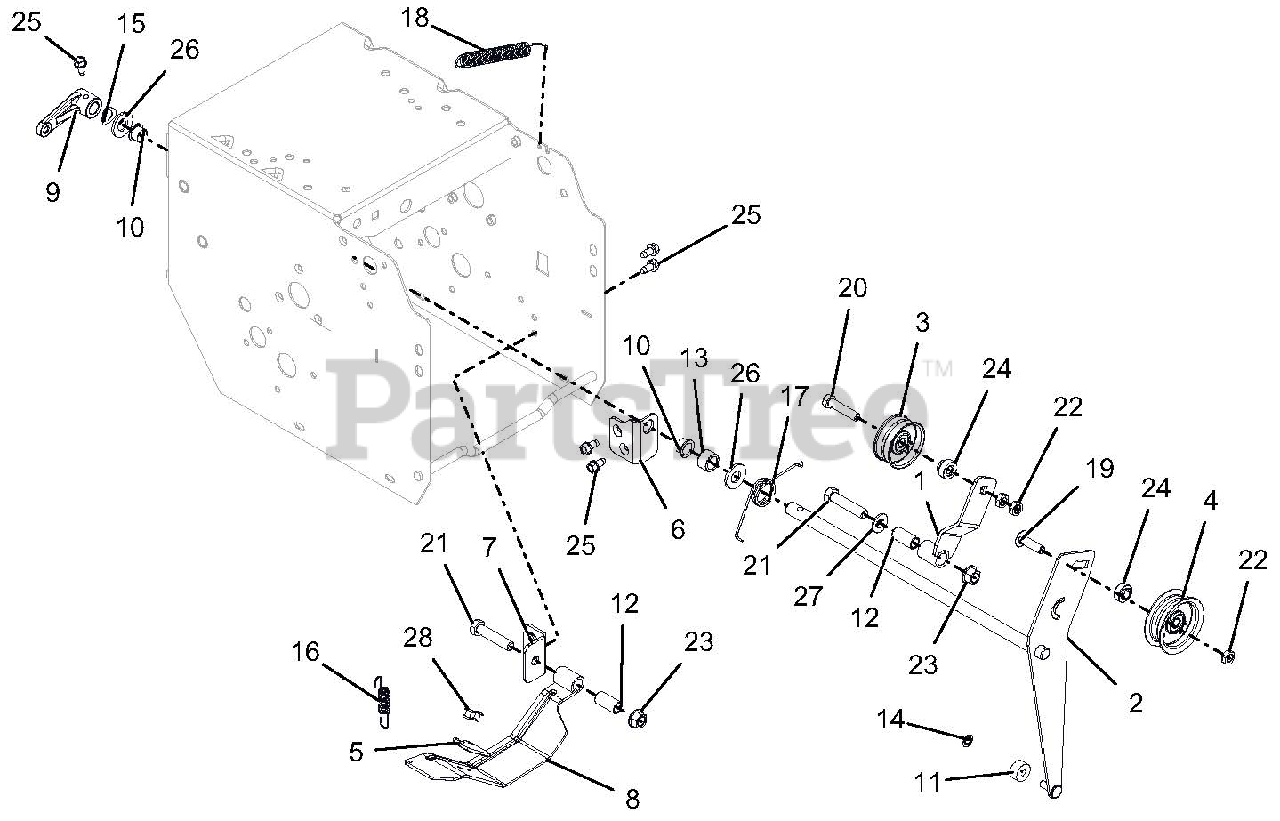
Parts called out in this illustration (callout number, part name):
1	ARM, TRACTION IDLER
2	WELDMENT, ATTACHMENT IDLER ARM
3	IDLER, FLAT - 1.875"
4	IDLER, FLAT - 2.00"
5	PAD, BRAKE
6	BRACKET, MOUNT - IDLER ARM
7	BRACKET, MOUNT - BRAKE
8	BRAKE ARM W/PAD
9	ARM, CLUTCH - ATTACHMENT
10	BUSHING, POLYLINER-.50 SPLIT
11	BSHG,SLV .265 X .625 X .375
12	BSHG-SLV .385X.500X1.045
13	BSHG-SLV .510X.751X.475
14	RG-RTNG-EXT .250X.010
15	WSHR-WAVE .50X.75X.015 .13FRHT
16	SPRING-EXT .437 X .438 X 2.64
17	SG-TORS .075 X .955
18	SPRING, EXTENSION
19	BLT-RDHDSQSHNK.31-18X1.13 G5YZ
20	@BLT-HEX .31-18X1.50 GR5 YWZC
21	@BLT-HEX .38-16X1.75 GR5 YWZC
22	@NUT-LK-CTR-JAM .31-18 YWZC
23	@NUT-LK-TOP-FLG .38-16 YWZC
24	BSHG-SLV .325X.49X1.56
25	SCR-TAP .25-20X.50 HWH TR YWZ
26	@WSHR-FL-STL.531X1.06X.095YWZC
27	@WSHR-FL-STL.406X.812X.065 YWZ
28	RVT-POP .187 YZ
